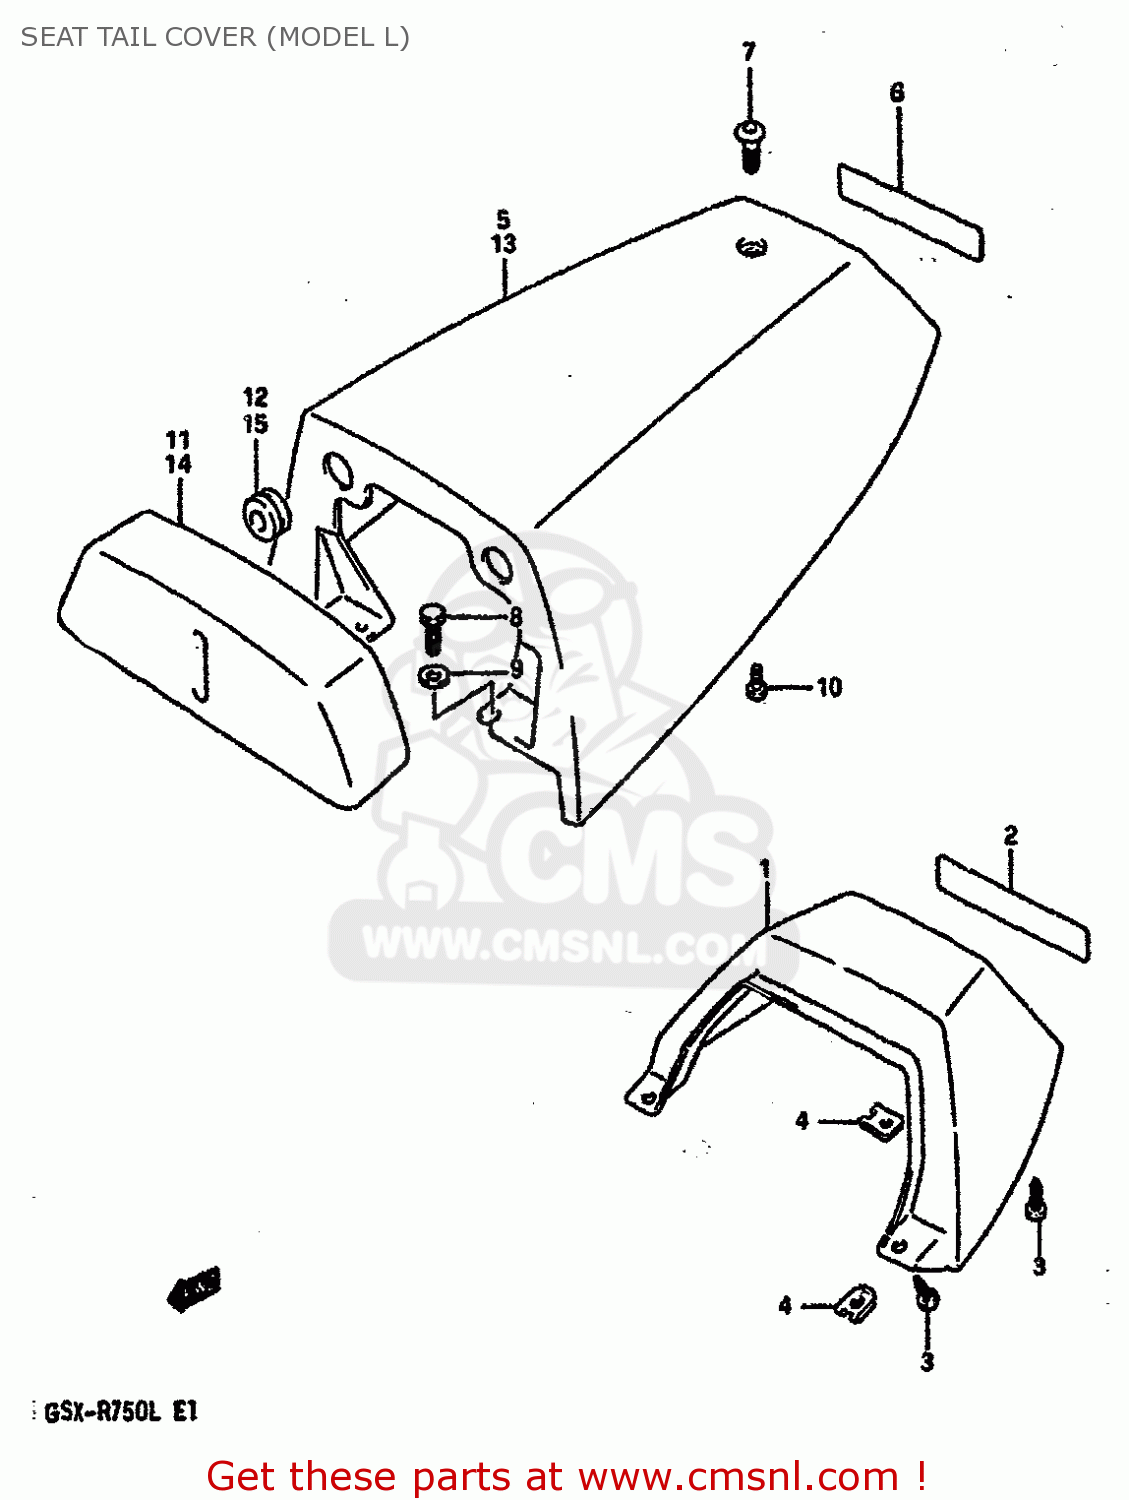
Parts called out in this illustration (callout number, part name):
1	COVER COMP,SEAT TAIL
2	EMBLEM
3	SCREW
4	NUT
5	BOX SET,SEAT TAIL
6	EMBLEM
7	SCREW(6X16)
8	BOLT,M6X1X20
9	WASHER, LOWER
10	SCREW
11	BACKREST,SEAT
12	CUSHION
13	BOX ASSEMBLY,SEAT TAIL
14	BACKREST,SEAT(BLACK)
15	CUSHION
18	BOLT,M6X1X20
19	WASHER, LOWER
20	SCREW
21	BOLT,M6X1X20
22	CUSHION
23	BOX ASSY,SEAT TAIL (BLACK)
24	EMBLEM
25	SCREW(6X16)
26	SCREW
27	BOLT,M6X1X20
28	WASHER,LOCK
29	BACKREST,SEAT
30	CUSHION
